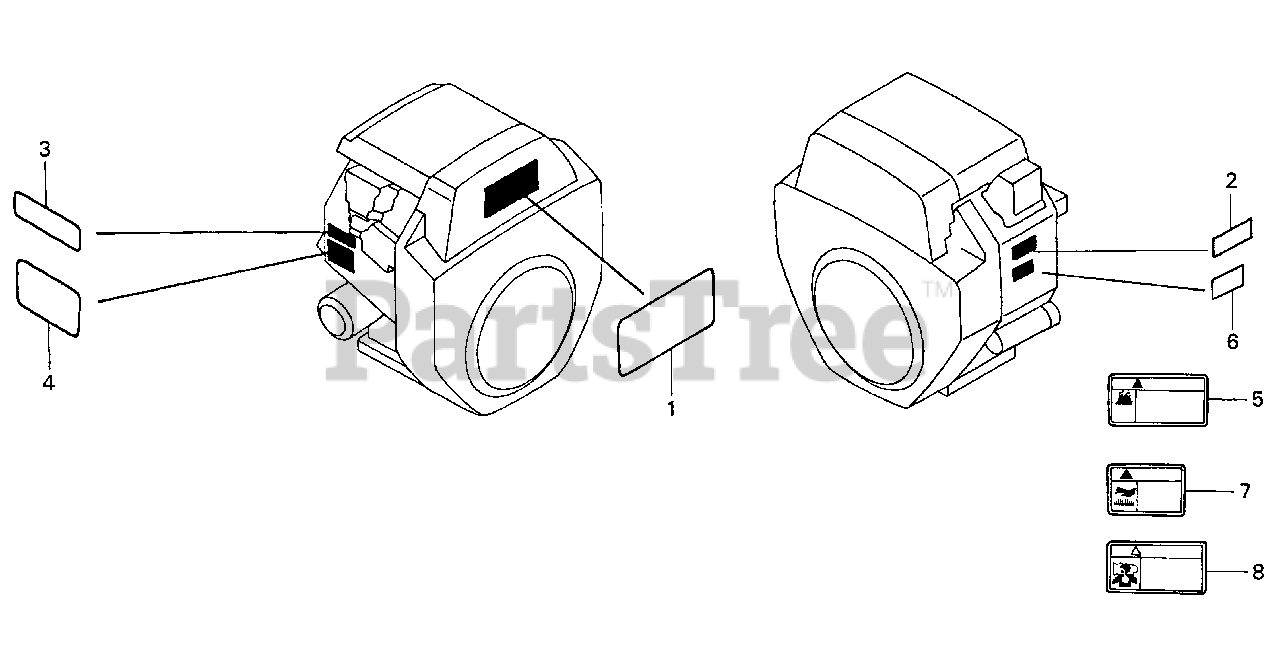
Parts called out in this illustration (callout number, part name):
1	MARK, EMBLEM (GX610)
2	MARK, OIL ALERT (E)
3	LABEL, SPECIFICATION (GX610)
4	LABEL, CAUTION
5	MARK, FUEL WARNING
6	MARK, CAUTION (J)
7	MARK, HEAT CAUTION
8	MARK, EX. GAS WARNING
